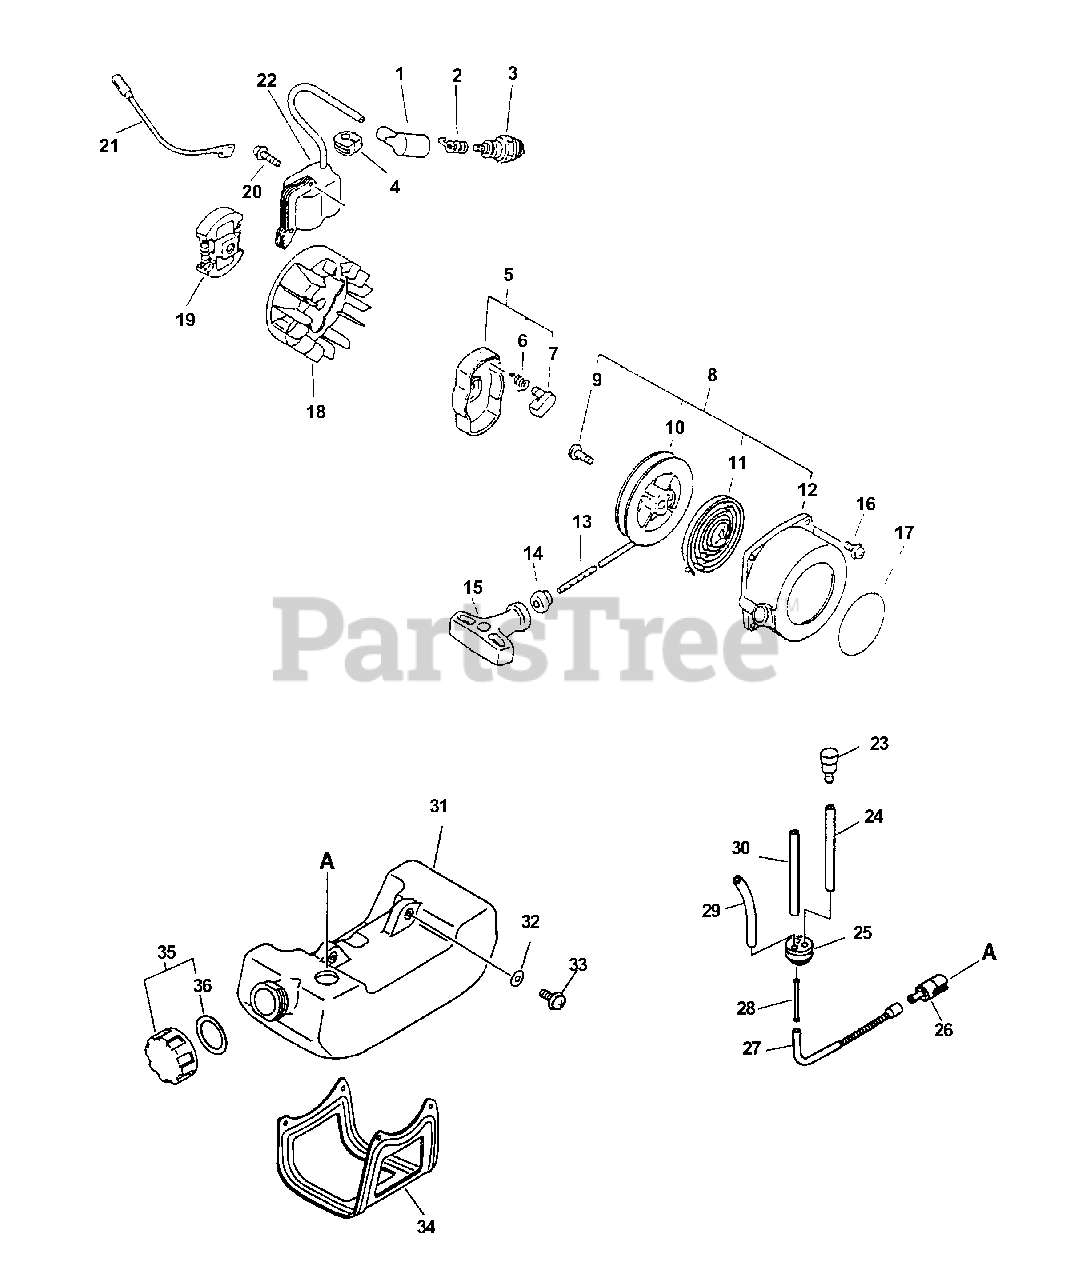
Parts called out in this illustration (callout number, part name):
1	CAP, SPARK PLUG
2	TERMINAL, SPARK PLUG
3	SPARK PLUG - BPM-7Y
3	SPARK PLUG - RCJ7Y
5	PAWL ASSY, STARTER
6	SPRING, RETURN
7	PAWL, STARTER - BLACK
8	STARTER ASSY, RECOIL
9	SCREW
10	REEL, ROPE
11	SPRING, RECOIL
12	CASE, RECOIL STARTER
14	GUIDE, ROPE
15	GRIP, STARTER
16	BOLT 4×16
17	LABEL, ECHO
19	CLUTCH ASSY
20	SCREW 4×22
21	LEAD
22	COIL, IGNITION
23	VENT ASSY
24	PIPE, FUEL 3x-5x-70 BLACK
25	GROMMET, FUEL
26	FILTER, FUEL
27	PIPE, FUEL 3×7×100 FLEXIBLE
28	CONNECTOR, PIPE
29	PIPE, FUEL RETURN 3×6×90 MM CLEAR
29	PIPE, FUEL 3×6×80 CLEAR
30	PIPE, FUEL 3x-5x-70 BLACK
31	TANK, FUEL
32	WASHER 5.5×12×0.8
33	SCREW 5×16
34	GUARD, FUEL TANK
35	CAP ASSY, FUEL
36	GASKET, FUEL CAP
